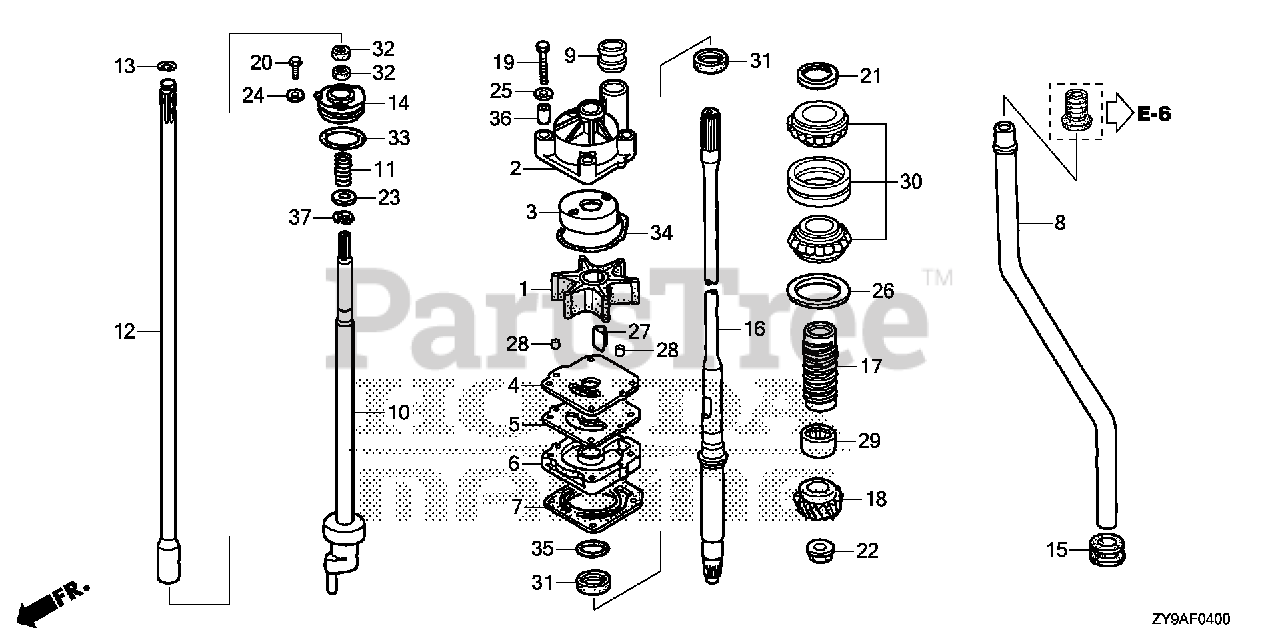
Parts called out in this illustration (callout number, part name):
1	IMPELLER, PUMP
2	HOUSING, IMPELLER
3	LINER, PUMP
4	COVER, IMPELLER
5	GASKET B, IMPELLER
6	HOUSING, WATER PUMP
7	GASKET, WATER PUMP
8	TUBE, WATER (L)
9	RING, WATER TUBE SEAL
10	ROD, SHIFT (L)
11	SPRING, SHIFT ROD
12	ROD A, SHIFT (L)
13	RING, STOPPER
14	HOLDER, SHIFT ROD
15	GROMMET, EXTENSION CASE
16	SHAFT, VERTICAL (L)
17	SLINGER, OIL
18	GEAR, PINION (12T)
19	BOLT, HEX. (8X55)
20	BOLT, FLANGE (6X12) Use from Frame SN 1005249.
21	NUT, LOCK (64MM)
22	NUT, HEX. (16MM)
23	WASHER, PLAIN (12MM)
24	WASHER, PLAIN (6MM)
25	WASHER (8MM)
26	SHIM A, GEAR (0.10)
26	SHIM B, GEAR (0.15)
26	SHIM C, GEAR (0.30)
26	SHIM D, GEAR (0.50)
27	KEY, WOODRUFF
28	PIN, DOWEL (6X10)
29	BEARING, NEEDLE (1-1/8X1-1/2X1-1/4)
30	BEARING, TAPER ROLLER (30X62X40)
31	SEAL, WATER (23X36X6) Use up to Frame SN 1300340.
31	SEAL, WATER (23X36X6)
32	SEAL, WATER (12X21X6)
33	O-RING (49.4X3.1)
34	O-RING, WATER PUMP
35	O-RING (58.5X3.5)
36	COLLAR, DISTANCE
37	E-RING (10MM)
